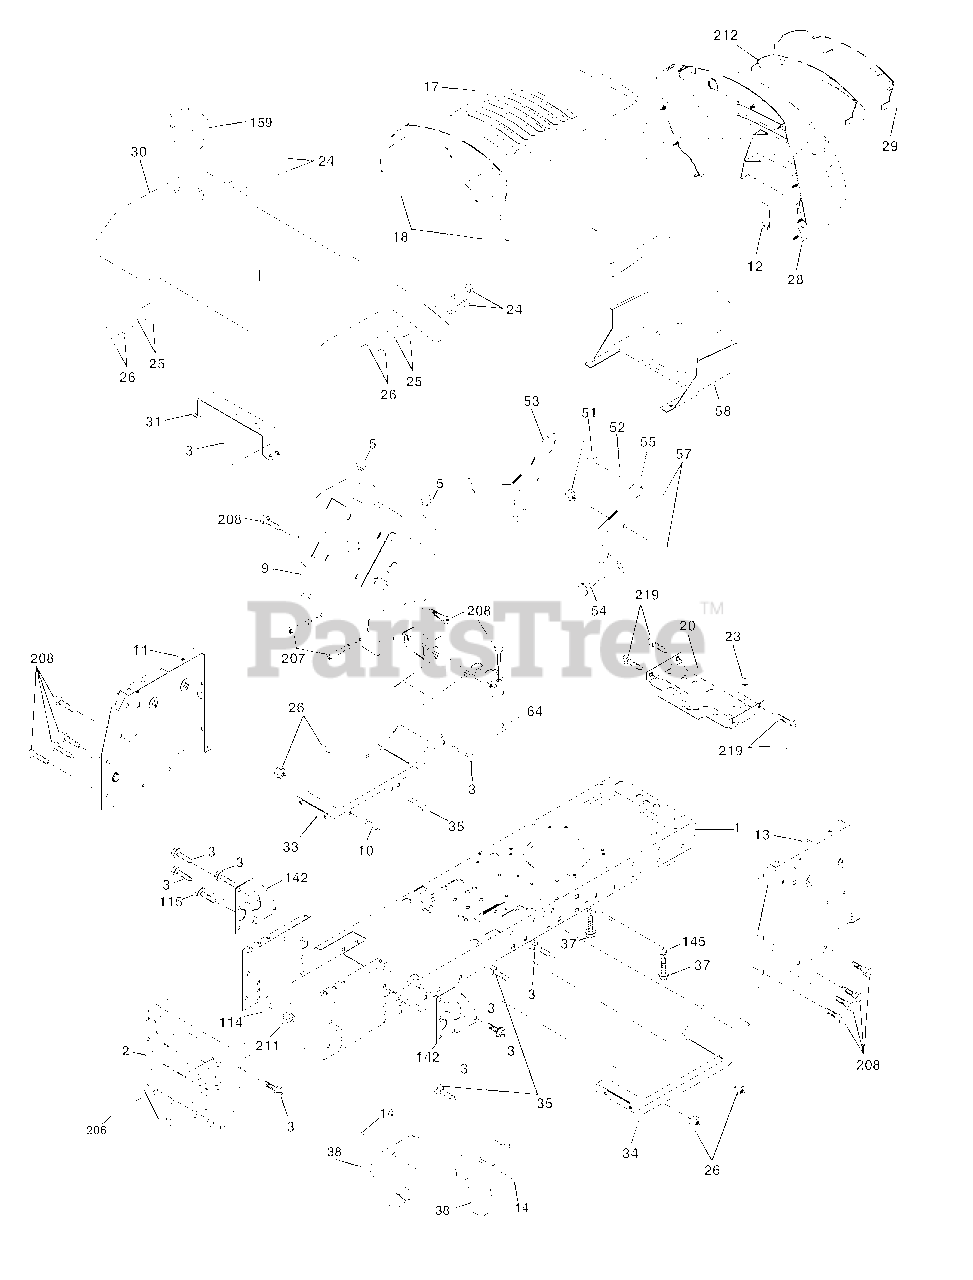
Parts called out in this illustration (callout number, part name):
1	Chassis
2	Drawbar
3	Screw 3/8-16 X .75
5	Bumper Hood/Dash
9	Dash P/L
10	Bolt Carriage 3/8-16 x 1
11	Panel Dash Lh
12	Clip Tinnerman
13	Panel Dash Rh
14	Screw Thdrol 3/8 x 16 x 1/2
17	Hood LT/PL
18	Bumper Hood
20	Plate Mtg Battery Fuel Tank Fr
23	Bushing
24	Bolt Fin Hex 3/8-16 x 1 Gr 5
25	Washer 13/32 X 13/16 X 12 Ga
26	Nut Lock Hex W/Ins 3/8-16 Unc
28	Grille/Lens Asm
29	Lens LT/PL
30	Fender Footrest Pnt
31	Bracket Fender
33	Footrest Pnt Lh
34	Footrest Pnt Rh
35	Bolt Rdhd Sht Sqnk 3/8-16 x 3/4
37	Screw Thdrol 6/16-18 x 1/2 TYT
38	Bracket Asm Pivot Mower Rear
51	Nut Lock Hex W/Ins 1/4-20
52	Washer 9/32 x 7/8 x 16 Ga.
53	Bracjet Grukke Lh
54	Screw Hex Wshd 8-18 x 7/8
55	Bracket Grille Rh
57	Bolt Hex 1/4-20 x 3/4
58	Duct Air
64	Dash Lower STLT
114	Keeper Belt Rear LH
115	Screw 3/8-16 x 1-1/4
142	Plate Reinforcement STLT
145	Rod Pivot Chassis/Hood
159	Cupholder
206	Bolt Shoulder 5/16-18
207	Screw Thdrol 5/16-18 x 1/2
208	Screw Thdrol 3/8-16 x 1/2
211	Nut Hexflange Lock
212	Insert Lens Relect
219	Screw 5/16-18 x 3/4
